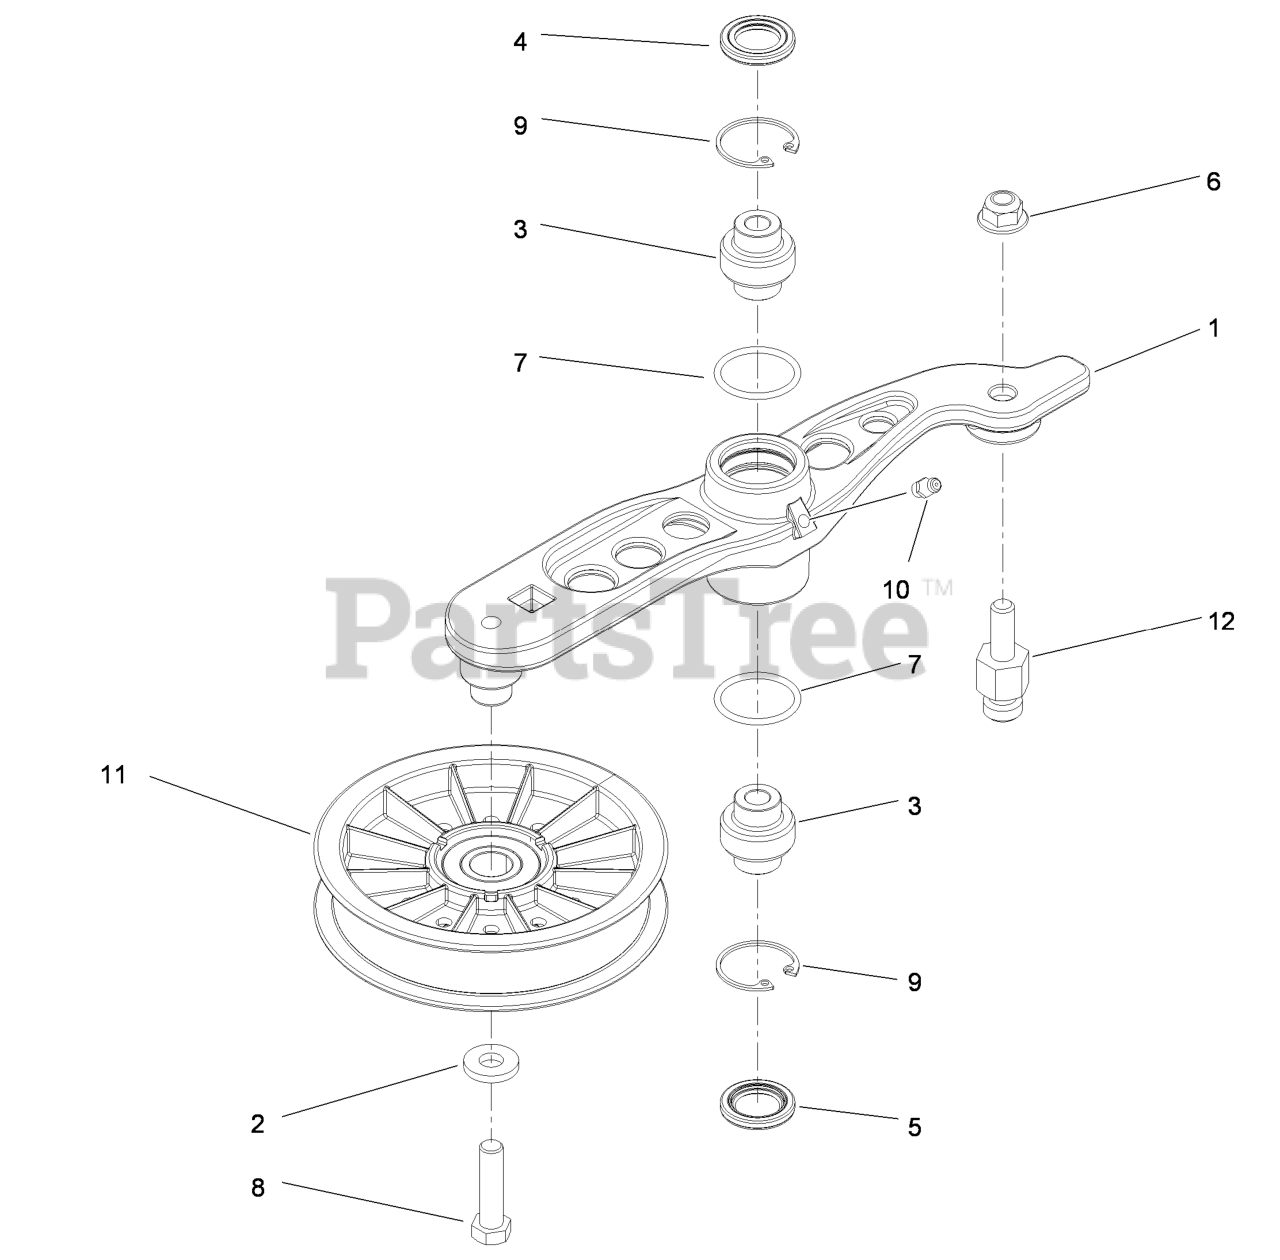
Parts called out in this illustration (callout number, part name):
1	Arm-Pump, Idler
3	BEARING-SPHERICAL
4	SEAL-LIP, DOUBLE
5	SEAL-LIP, SINGLE
6	Nut-Nyloc 3/8-16 Flg
8	SCREW-HH
9	RING-SNAP
10	FITTING-GREASE
11	PULLEY-IDLER
